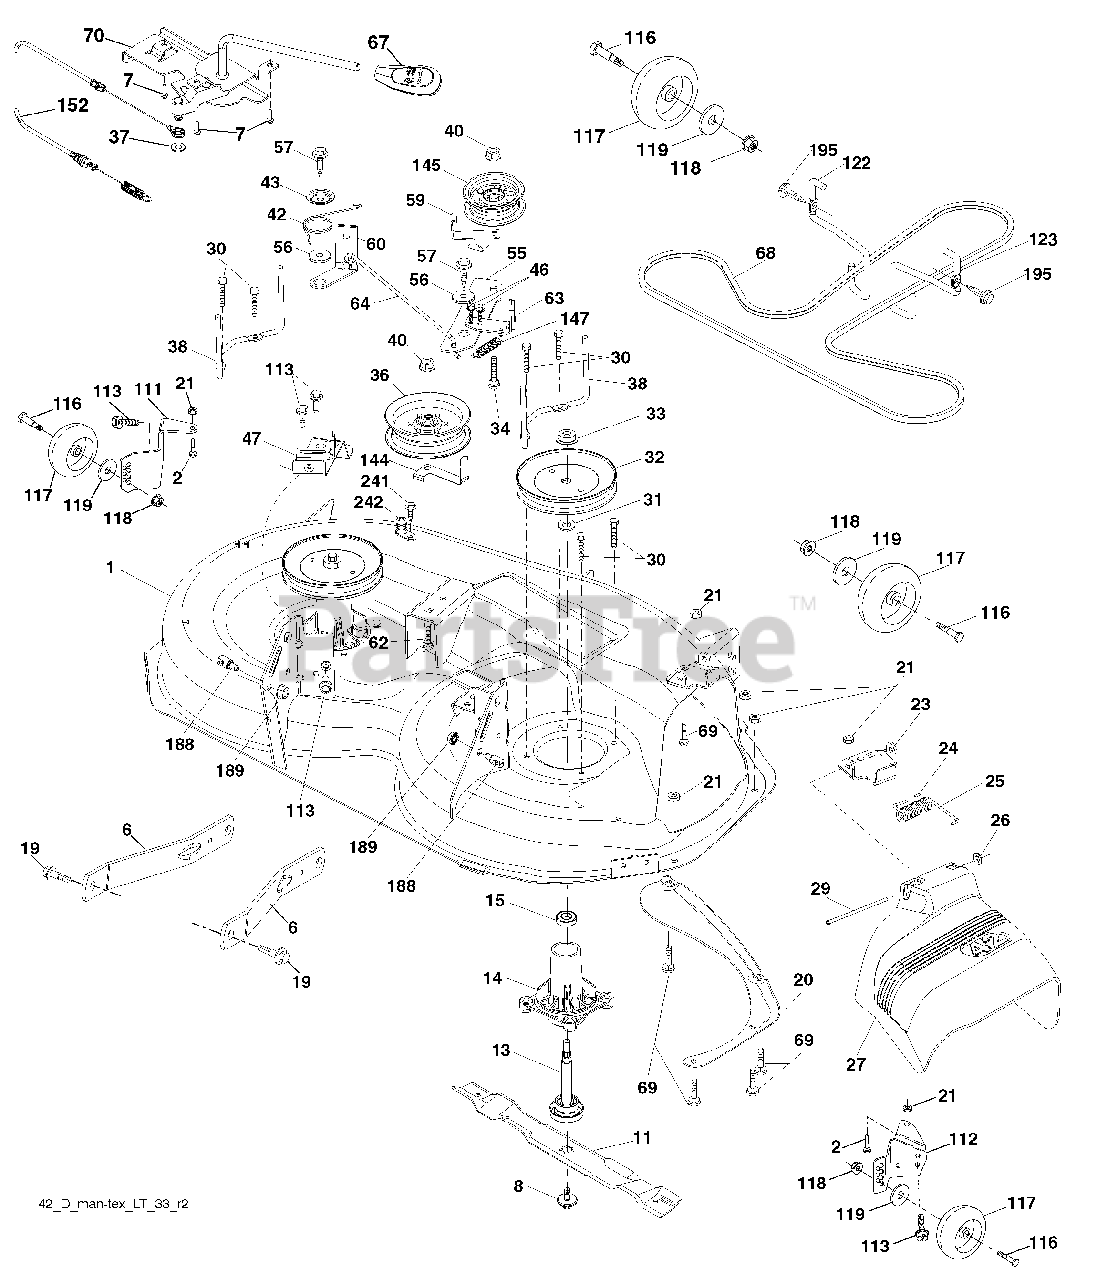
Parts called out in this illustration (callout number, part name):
1	Mower Housing
2	Bolt Rdhd 5/16-18 x 3/4
6	Arm Suspension
7	Screw #10 x 0.750 BOS Thread
8	Bolt/Washer Asm 7/16-20 unf
11	Blade, 42" Hi-Lift (For bagging or discharge)
11	Blade, 42" Mulching Premium (For better wear when mulching)
11	Blade, 42" Mulching Std (For mulching mowers only)
11	Blade 42SP" 3N1
11	Blade 42SP" Premium
13	Shaft Assembly, Mandrel
14	Housing, Mandrel
15	Bearing, Ball, Mandrel
19	Bolt, Shoulder
20	Baffle, Vortex
21	Nut, Crownlock 5/16-18 unc
23	Bracket, Deflector
24	Cap, Sleeve
25	Spring, Torsion, Deflector
26	Nut, Push
27	Shield, Deflector
29	Rod, Hinge
30	Screw Thdrol Rolling Wsh Hd
31	Washer, Spacer
32	Pulley, Mandrel
33	Nut, Toplock, Flanged
34	Bolt Carr Sh. 3/8-16 x 1-1/2 Gr. 5
36	Pulley, Idler 4.50 RAW
37	Washer 13/32 x 13/16 x 16 Ga.
38	Keeper Belt LH Mandrel
40	Nut, Lock Flg. 3/8-16 unc
42	Spring Torsion Brake
43	Spring Torsion Retainer
46	Screw Thd Roll 1/4-20 x 5/8
47	Bracket Clutch Cable
55	Arm, Idler
56	Spacer, Retainer
57	Screw Hexwsh Thd 3/8-16 x 1
59	Guard, Tuv Idler (94)
60	Arm Brake Mower
62	Bolt Rdhd Sqnk 3/8-16 unc x 2
63	Arm Brake Mower
64	Linkage Brake
67	Handle, Clutch Cable
68	V-Belt
69	Bolt Rdhd Sqnk 5/16-18 x 5/8
70	Clutch Asm. Manual
111	Bracket Wheel Gauge LH
112	Bracket Wheel Gauge RH
113	Screw 5/16-18
116	Bolt Shoulder "A" 2.41 "B" 1.66
117	Wheel Gage
118	Nut Centerlock 3/8-16 unc
119	Washer 3/8 x 7/8 x 14 Ga.
122	Keeper Belt Eng. LH
123	Keeper Belt Eng. RH
144	Keeper Belt
145	Pulley Idler Primary
147	Spring Return
152	Cable Clutch Manual w/Spr.
188	Stud Fastener
189	Nut Lock Hex Flange
192	Bracket Brake Stand LH
195	Screw Hexwsh Thdr 3/8-16 x 3/4
241	Screw #10-32.5 3/8 Flange
242	Port Washout
242	Mandrel Assembly
242	Replacement Mower, Complete
